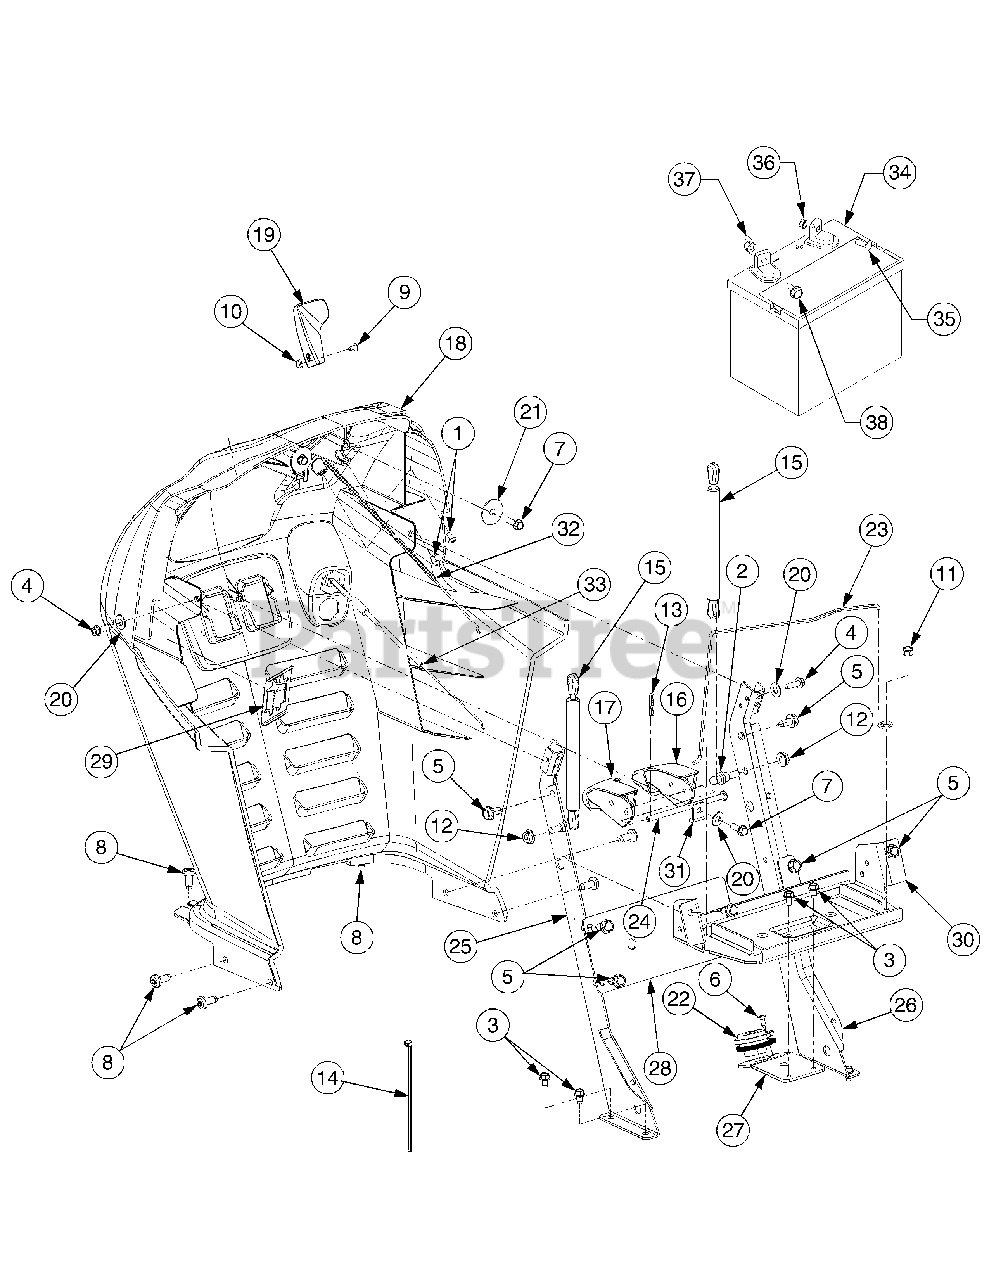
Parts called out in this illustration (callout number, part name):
1	Screw, #10-24 X .375
2	Screw, Ball, 5/16-18
3	Screw, Self-tapping, 1/4-20, 0.500
4	Screw, Hx. Wash. Hd, Tapp. 1/4-20 x .75
5	Screw, Hx. Wash. Hd, Tapp, 5/16-12 x .75
6	Screw, Oval Cntrsnk, #10-16 x .625
7	Screw, 1/4-15, 0.750
8	Screw, Torx Hd. Tapp. 5/16-18 x .75
9	Screw, Truss Mach., #8-32 x .375
10	Nut, Hex, #8-32 GrA
11	Nut, Hex Insert Lock, 1/4-20 GR8
12	Nut, Hex Flange Lock, 5/16-18 GR5
13	Internal Cotter Pin, .072 x 1.13
14	Cable Tie
15	Cylinder, Gas
16	Lever, Dash, Brake
17	Lever, Dash, Cruise
18	Dash
18	Graphic, Dash Insert
19	Knob, Throttle Control
20	Washer, Flat, .28 x .74 x .063
21	Washer, Flat, .33 x 1.25 x .06 HT
22	Bearing, Steering Column
24	Rod, .25 x 4.55
32	Cable, Throttle, 38.0 Lg
33	Cable, Choke, 40.5 Lg.
34	Battery, 235 CCA, Dry
35	Screw, Carriage, 1/4-20, .75,
36	Nut, Hex, 1/4-20, Sems
37	Nut, Wing, 1/4-20
38	Screw, Shoulder, 1/4-20, .25 x .15
